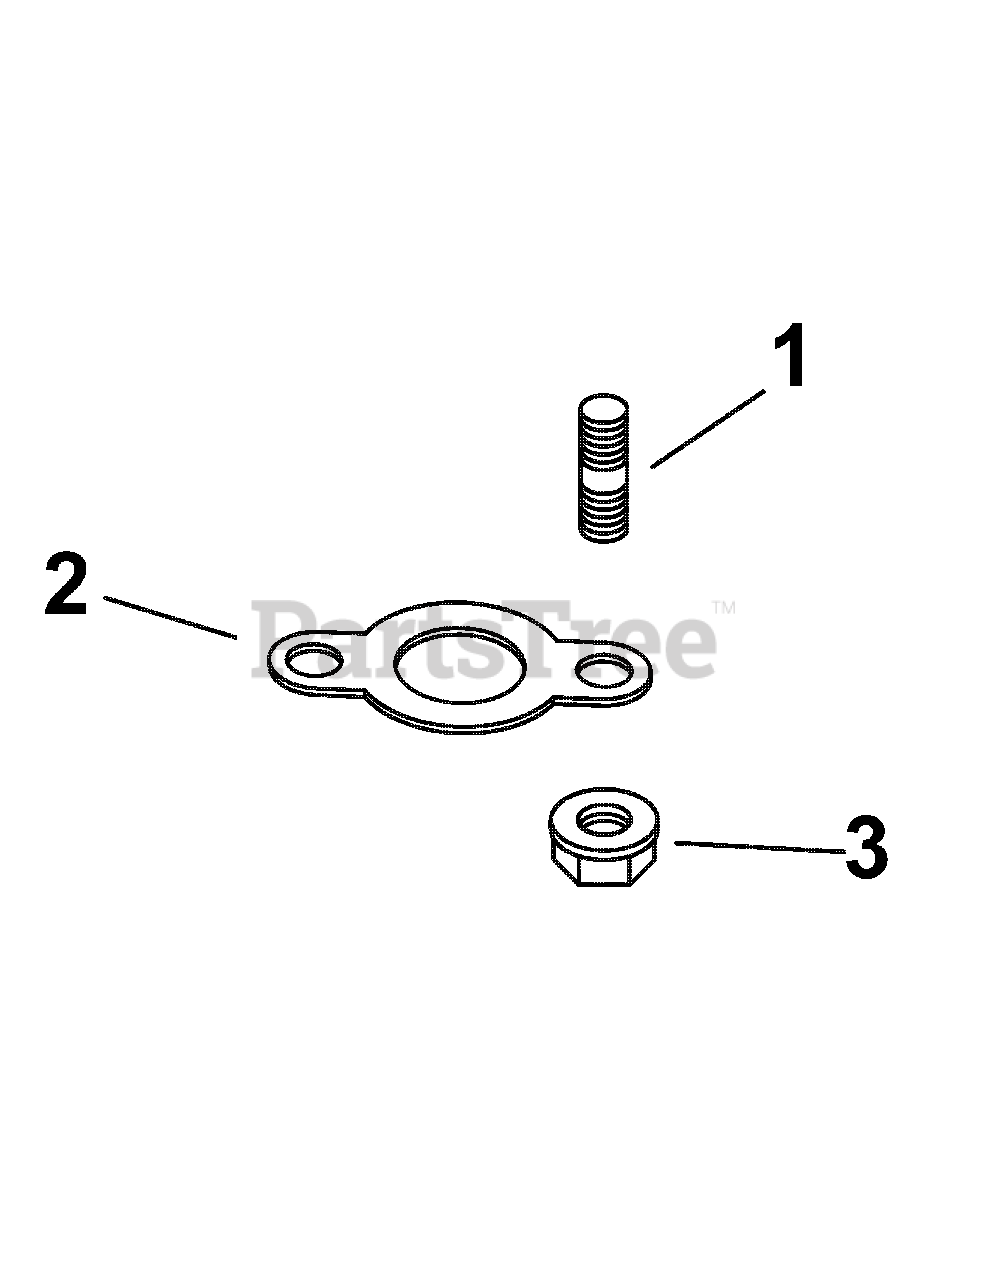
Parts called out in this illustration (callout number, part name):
1	Stud, M8 x 1.25 x 33
2	Gasket, Exhaust
3	Nut, Flg M8 x 1.25
